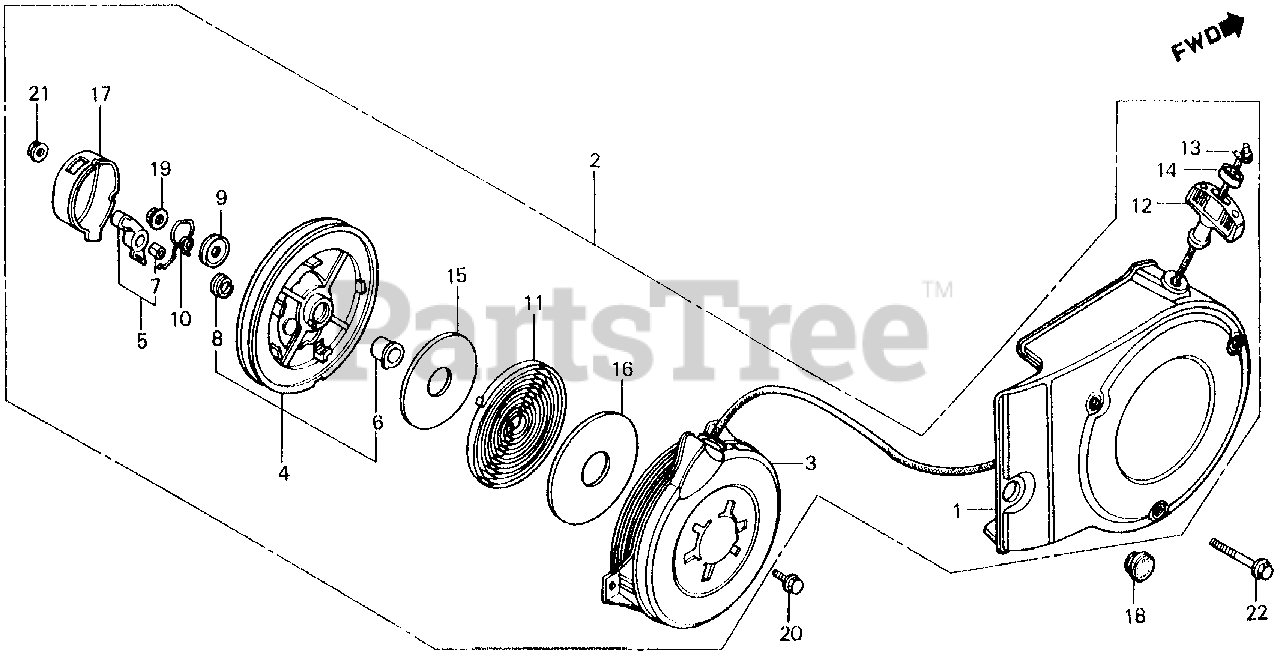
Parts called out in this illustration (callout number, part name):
1	COVER, RECOIL STARTER *R8* (BRIGHT RED) (NOT AVAILABLE)
2	STARTER ASSY., RECOIL *R8* (BRIGHT RED) (NOT AVAILABLE)
3	CASE, STARTER (NOT AVAILABLE)
4	REEL, STARTER
6	BOSS, REEL
7	BUSH, RATCHET
8	BUSH, REEL STARTER
9	PLATE, FRICTION
10	SPRING, FRICTION
11	SPRING, RETURN
12	GRIP, STARTER
13	ROPE, RECOIL STARTER (#5X55")
14	SUPPORT, GRIP
15	PLATE A, SIDE
16	PLATE B, SIDE
17	COVER, REEL STARTER
18	GROMMET, CABLE (C)
19	NUT, SELF-LOCK (8MM)
20	BOLT-WASHER (6X10)
21	NUT, FLANGE (5MM)
22	BOLT, FLANGE (6X65)
